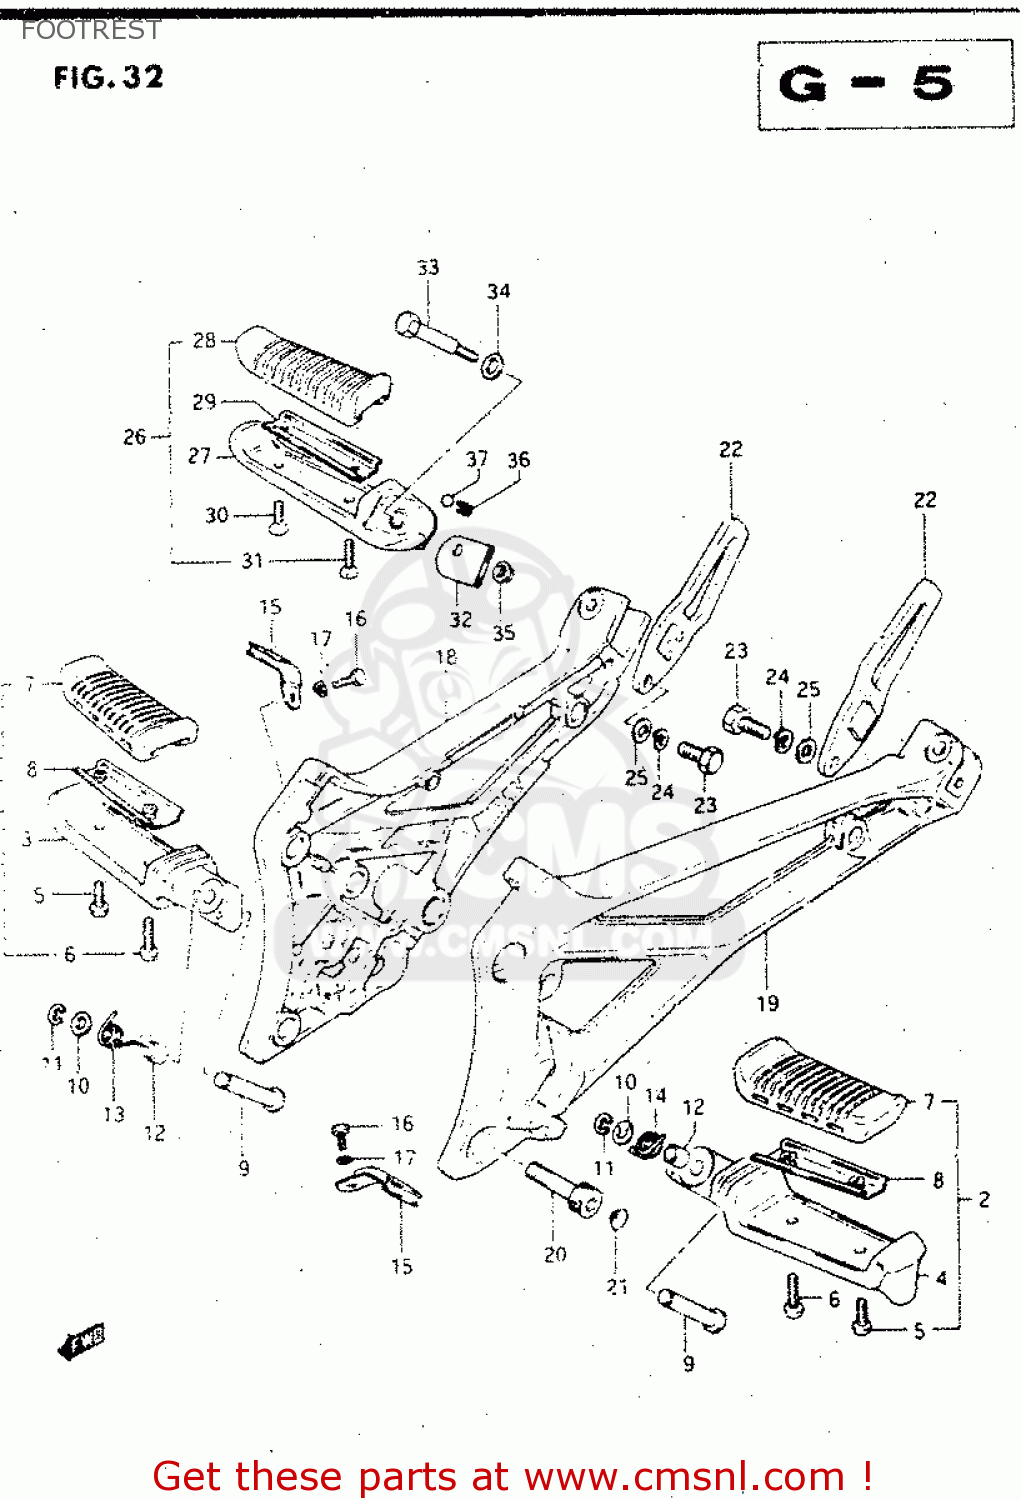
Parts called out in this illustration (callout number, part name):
1	FOOTREST ASSEMBLY,FRONT,RIGHT
2	FOOTREST ASSEMBLY,FRONT,LEFT
3	BAR,FRONT FOOTREST
4	FOOTREST,FRONT,LEFT
5	SCREW
6	SCREW
7	RUBBER,FOOTREST
8	PLATE,FR FOOTREST RUBBER
9	PIN
10	WASHER
11	E RING
12	BUSHING
13	SPRING
14	SPRING
15	CUSHION,FR FOOTREST
16	BOLT 5X10
17	LOCK WASHER
18	BRACKET,MUFFLER,RIGHT
19	BRACKET,MUFFLER,LEFT
20	BOLT 10X27
21	CAP
22	GUIDE,REAR FOOT
23	BOLT
24	LOCK WASHER
25	WASHER
26	FOOTREST ASSY,PILLION,R
27	BAR,PILLION FOOTREST,LEFT
28	RUBBER,RR FOOTREST
29	PLATE,RUBBER STOPPER
30	SCREW 5X12
31	SCREW 5X16
32	PLATE,SPRING STOP,R
33	BOLT
34	WASHER
35	NUT
36	SPRING
37	BALL
